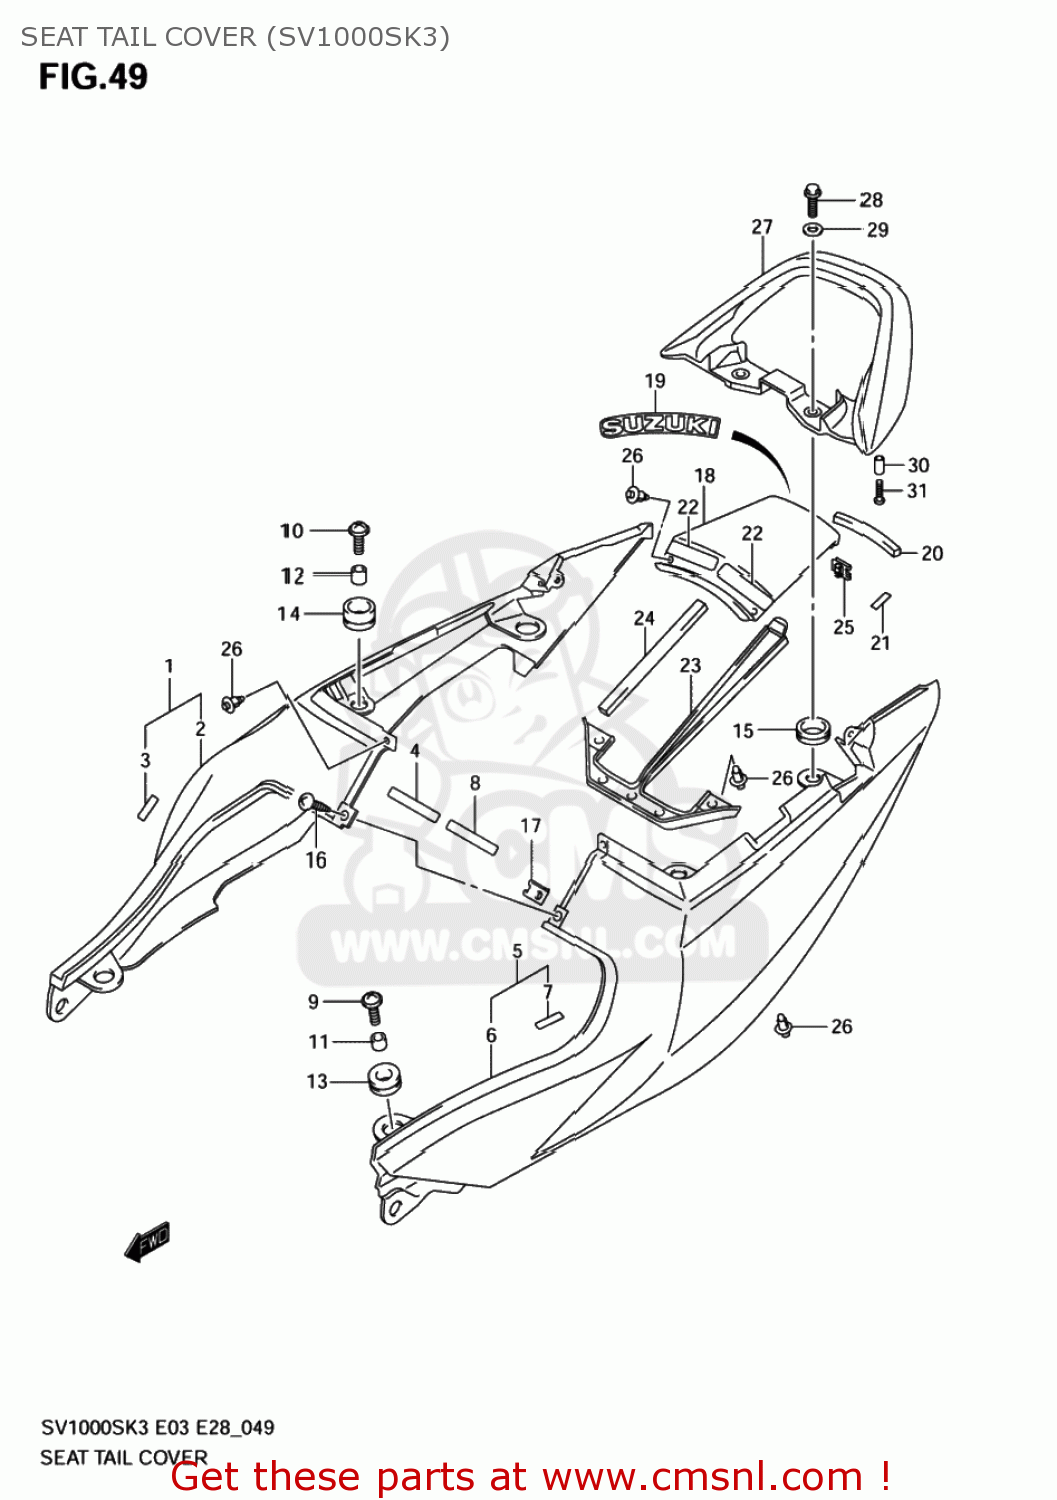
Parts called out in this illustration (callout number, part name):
1	COVER SET,SEAT
2	COVER SET,SEAT
3	TAPE,COVER
4	TAPE,SEAT TAIL COVER NO.2 FR
5	COVER SET,SEAT
6	COVER SET,SEAT
7	TAPE,COVER
8	TAPE,SEAT TAIL COVER NO.2 FR
9	SCREW(6X20)
10	SCREW(6X20)
11	SPACER(6.5X10X9.4)
12	SPACER(6.5X10X9.4)
13	CUSHION
14	CUSHION
15	CUSHION
16	SCREW
17	NUT
18	COVER,SEAT TAIL CTR
19	EMBLEM,SUZUKI
20	CUSHION,SEAT TAIL COVER CTR
21	TAPE,SEAT TAIL COVER
22	TAPE,COVER
23	COVER,SEAT TAIL RR
24	CUSHION,SEAT TAIL COVER
25	NUT
26	CLIP(BLACK)
27	HANDLE,PILLION RIDER
28	BOLT
29	WASHER(8.5X24X2.3)
30	SPACER(6.5X9X18)
31	SCREW(6X25)
